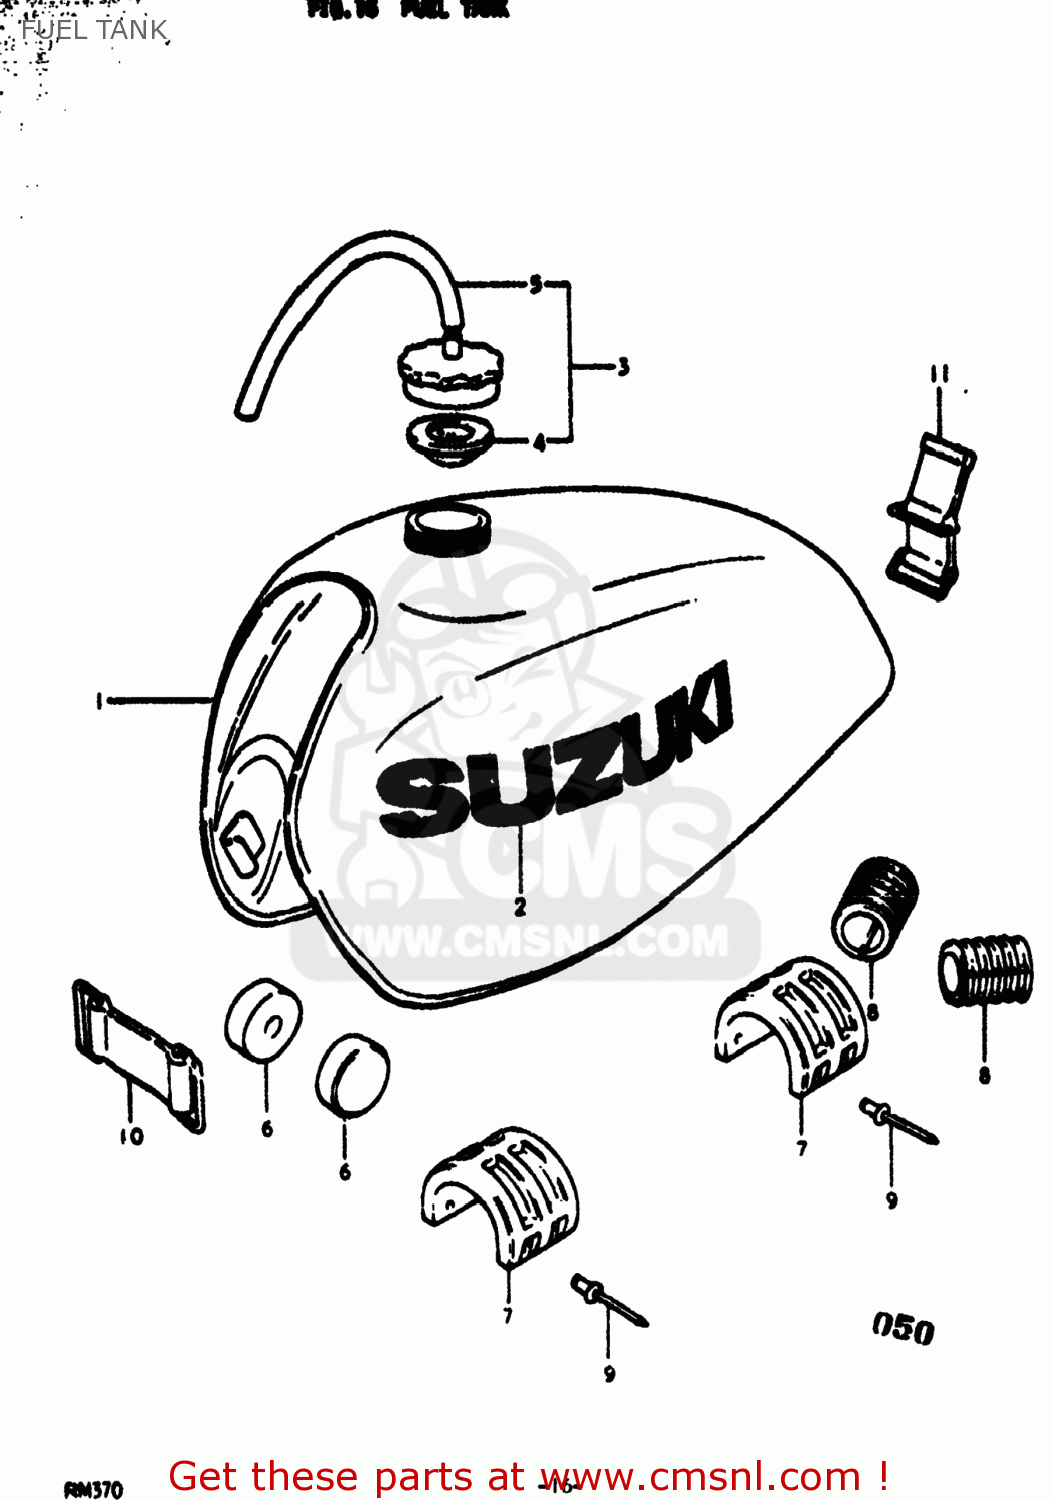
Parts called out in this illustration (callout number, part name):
1	TANK ASSEMBLY,FUEL
2	EMBLEM
3	CAP ASSY,FUEL TANK FILLER
4	GASKET,FUEL TANK CAP (NAS)
5	HOSE
6	CUSHION
7	CUSHION,FUEL TANK,CENTER
8	CUSHION,FUEL TANK,FRONT
9	RIVET
10	BAND
11	BAND
